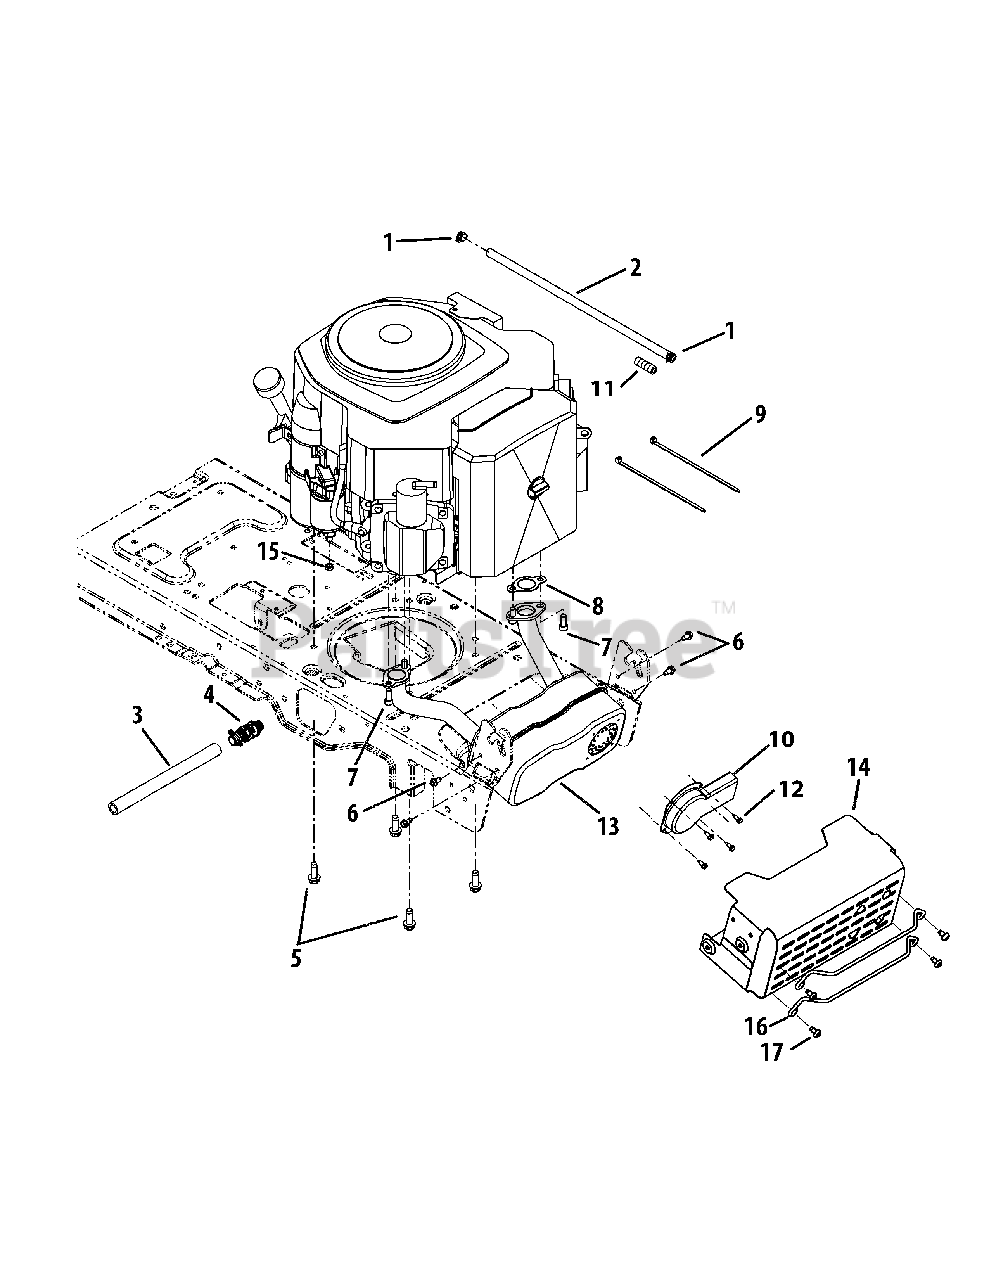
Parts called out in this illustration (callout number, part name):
1	Hose Clamp
2	Fuel Line 16" Lg.
3	Oil Drain Hose
4	Oil Drain
5	TT Screw 3/8-16 x 1.00
6	Hex Wash S-Tapp Scr 1/4-20 x .50
7	Scr. 5/16-18 x .75
8	Exhaust Gasket
9	Cable Tie
10	Long Muffler Deflector
11	Vent Hose
12	Hex AB Scr #8-18 x .50
13	Muffler
13	Muffler Guard Rod
14	Muffler Shield Assembly
15	Hex Sems Nut 1/4-20
18	TT Pan Hd Scr. 1/4-20 x .50
